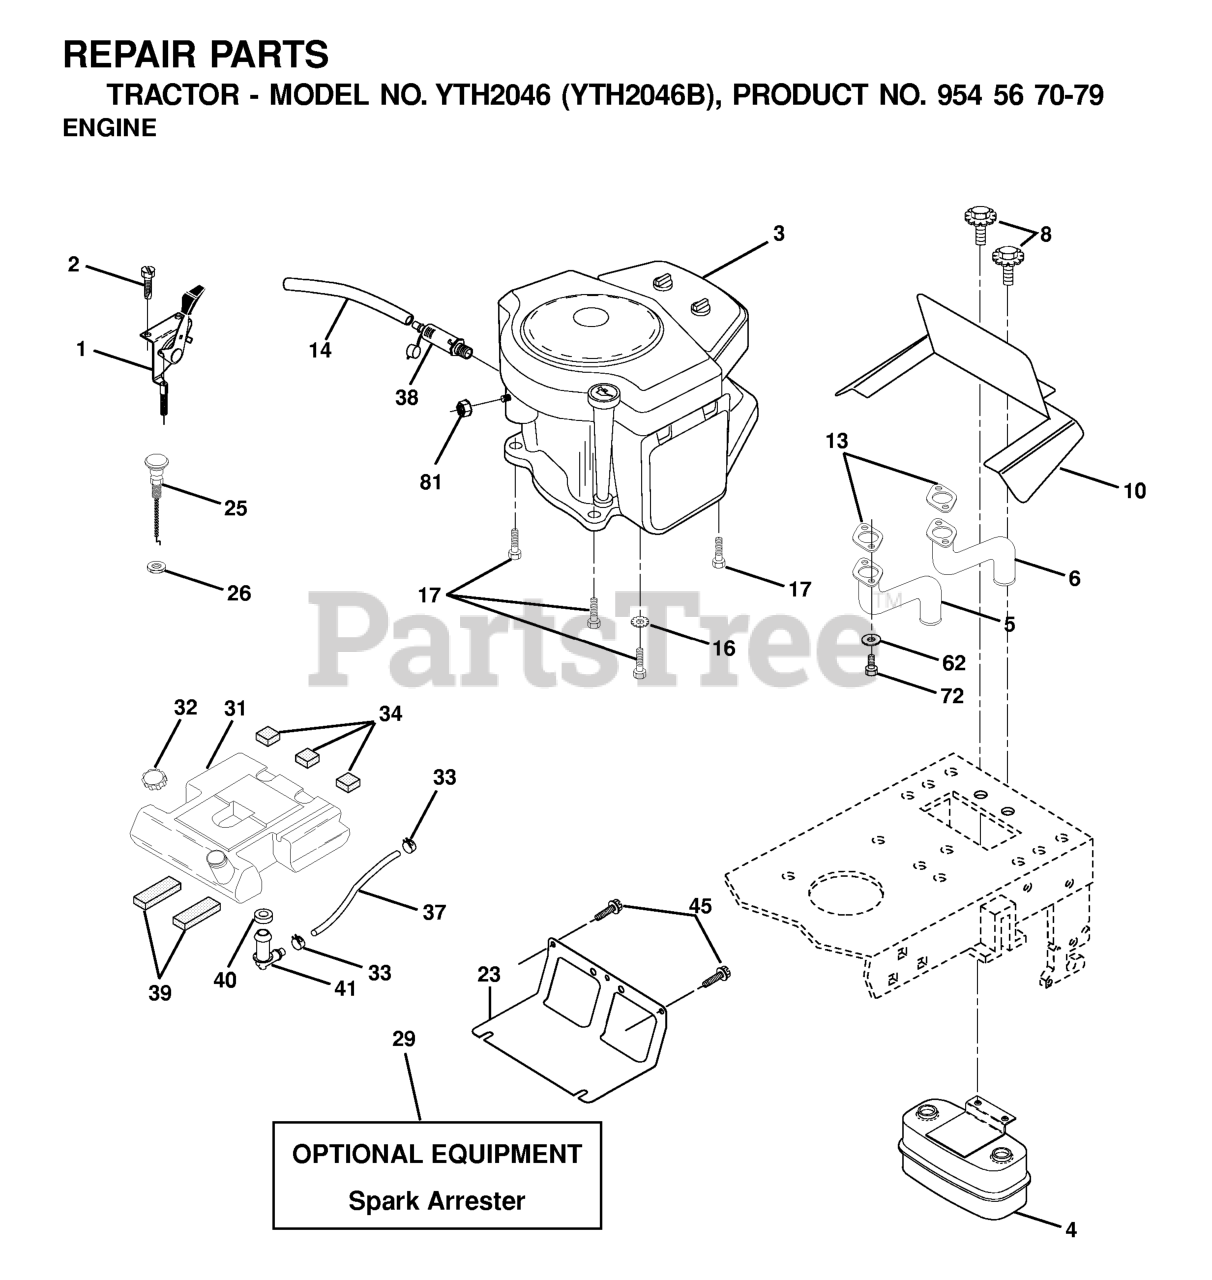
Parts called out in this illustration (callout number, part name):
1	CONTROL, THROTTLE
2	SCREW LT
4	MUFFLER.TWIN.CYL.LOW.TONE
5	RP.EXHAUST.TUBE.LH.BS/TWIN
6	EXHAUST.TUBE.RH.BS/TWIN
8	BOLT.5/16-18UNCX3/4 W/SEMS.BLK
10	SHIELD.BROWNING.B&S
13	GASKET.MUFFLER
14	TUBE, DRAIN OIL ASM.
16	LOCKWASHER
17	SCREW LT
23	SHIELD.BROWNING.DBR.GUARD
25	CONTROL, CHOKE
26	Nut Keps 3/8 - 24 UNF
29	KIT.SPARK ARRESTOR 794945 B&S
31	FUEL TANK 3.5G
32	FUEL CAP
33	HOSE CLAMP
34	PAD-SPACER LT
37	REPL BY 532 00 85-43
38	PLUG, OIL DRAIN EASY
39	PAD IDLER TI
40	BUSHING OUTLET T
41	STEM FUEL TANK
45	SCREW, 3/8-16X3/4
62	WASHER.LOCK.HVY.HLCL.SPR.5/16
72	SCREW
81	NUT
